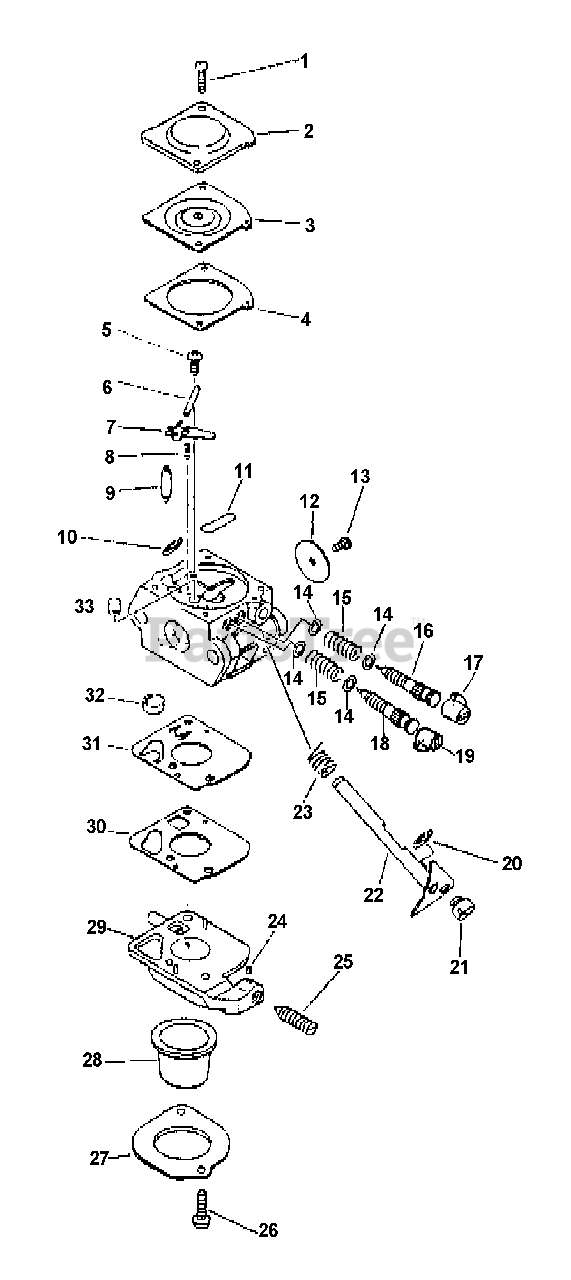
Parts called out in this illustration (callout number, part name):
2	COVER, METERING
3	DIAPHRAGM, METERING
4	GASKET, METERING
5	SCREW, METERING LEVER PIN
6	PIN, METERING LEVER
7	LEVER, METERING
8	SPRING, METERING LEVER
9	VALVE, NEEDLE
10	RING, RETAINING
11	PLUG, WELCH
12	VALVE, THROTTLE
16	NEEDLE - LOW SPEED
17	CAP, LIMITER
18	NEEDLE - HIGH SPEED
19	CAP, LIMITER
20	RING, RETAINING
22	SHAFT, THROTTLE
23	SPRING, RETURN
24	PIECE, FRICTION
25	SCREW, IDLE ADJUST
26	SCREW, RETAINER
27	RETAINER, PURGE BULB
28	BULB, PURGE
29	BASE, PURGE
30	GASKET, PURGE
31	DIAPHRAGM, PURGE
32	STRAINER
33	NOZZLE, CHECK VALVE
